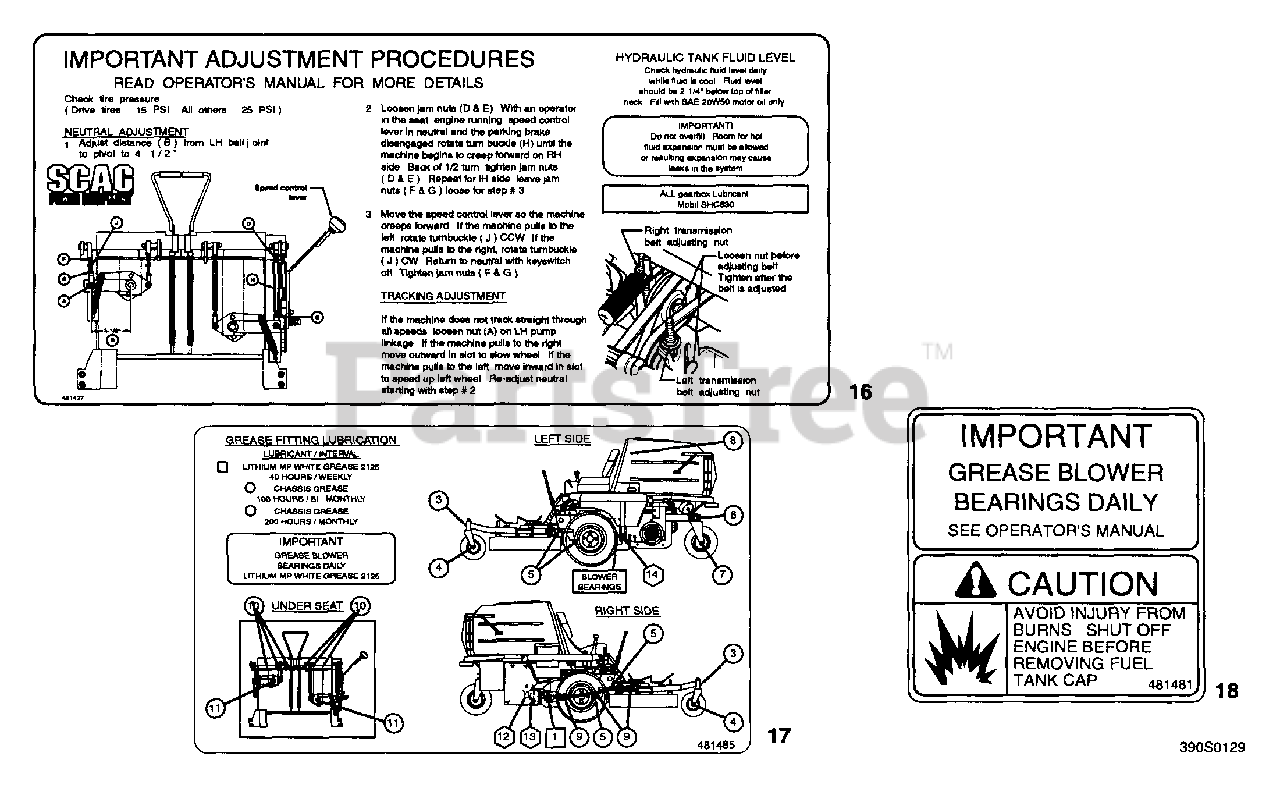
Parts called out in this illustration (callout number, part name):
16	Decal, Seat Base
17	Decal, Grease Points
18	Decal, Grease Daily
